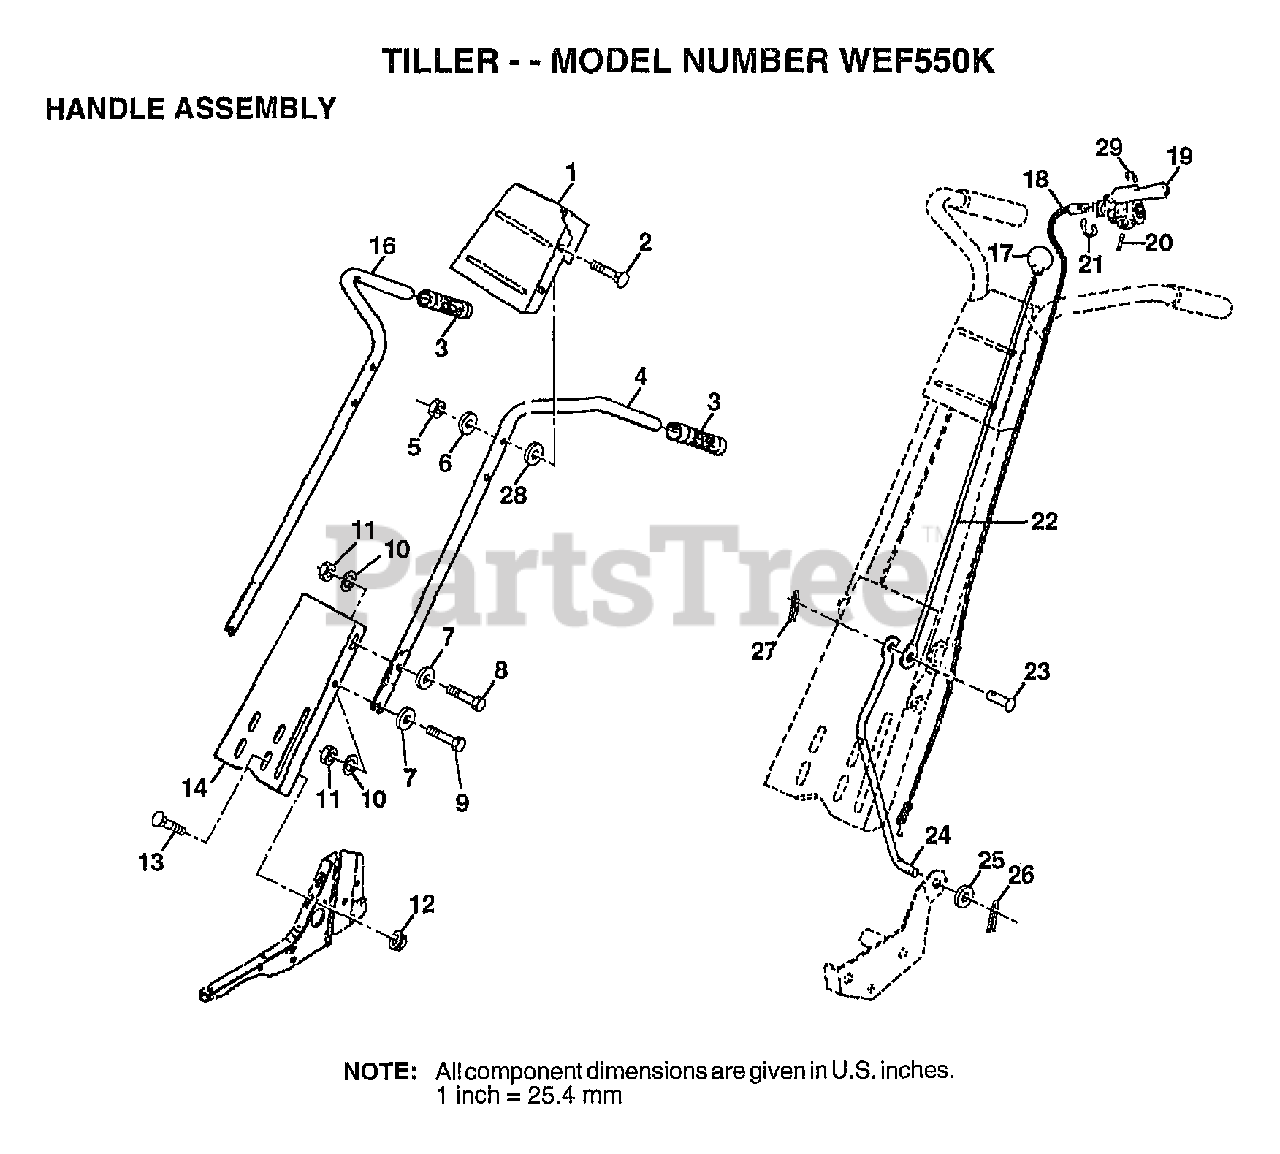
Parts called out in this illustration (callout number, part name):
1	BRACKET.HDLE.TILL
2	BOLT
4	HANDLE.LH TILLER
6	WASHER
7	WASHER
9	BOLT
10	LOCKWASHER
11	NUT.HEX.5/16-18
12	NUT
13	BOLT
14	PANEL.HANDLE.PNT.
16	"HANDLE-RH,TILLER"
17	KNOB T(3/8 HOLE)
18	CABLE CLUTCH T
19	LEVER CONTRL TINE
20	"PIN PIVOT,GROOVED"
21	E-RING
22	ROD REVERSE TI
23	RIVET.RD.HD.DRILL
24	REVERSE ROD TI
25	WASHER
26	COTTER PIN
28	WASHER
29	RETAINER RING
